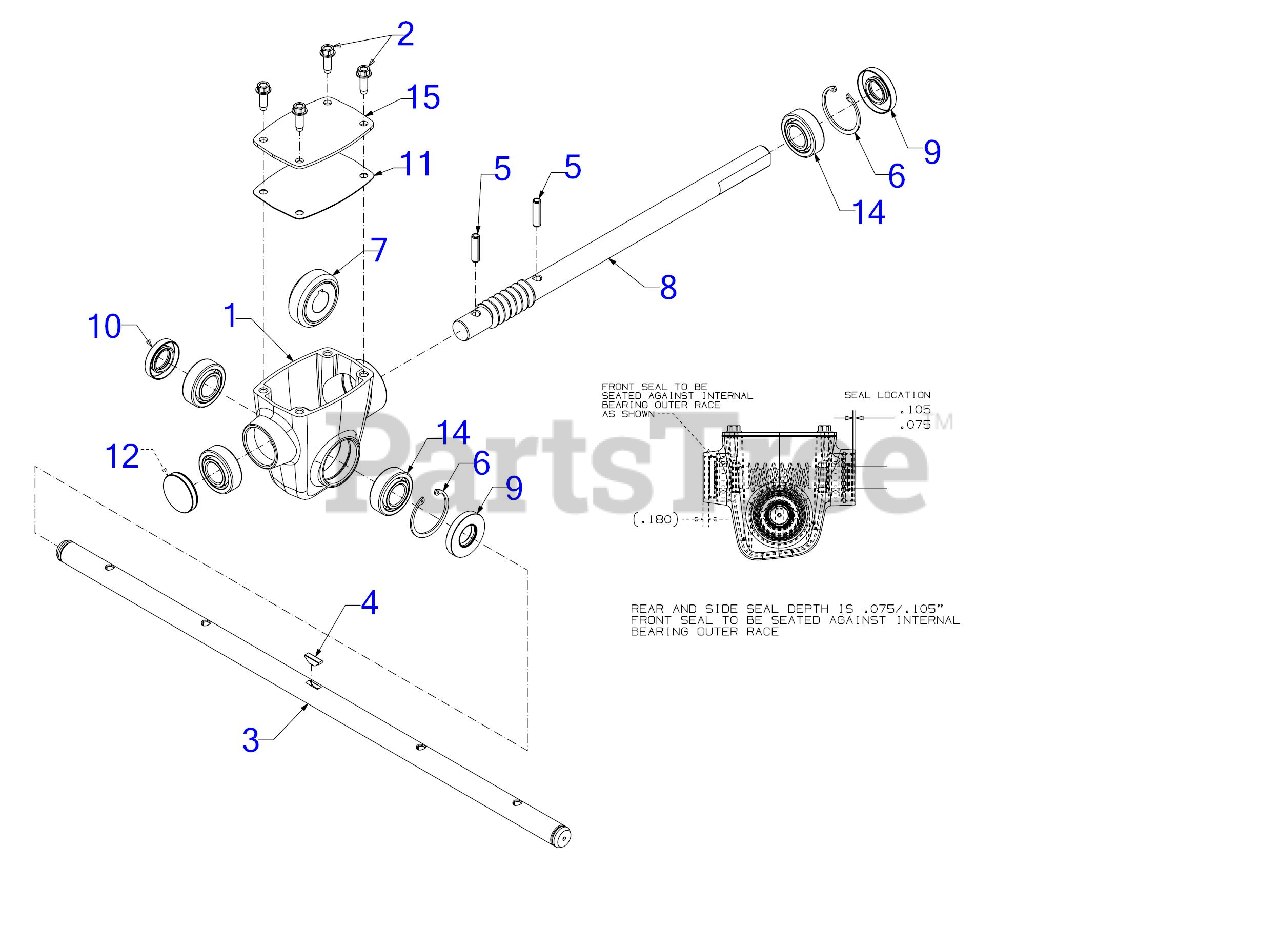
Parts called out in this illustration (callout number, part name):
1	AUGER GEARBOX HOUSING
2	SCREW 1/4-20 x .750
3	24" AUGER SHAFT
4	KEY 3/16 x 5/8 H
7	WORM GEAR 20T
8	WORM SHAFT
11	GEARBOX COVER GASKET
12	GEARBOX PLUG
14	BALL BEARING
15	GEARBOX COVER
